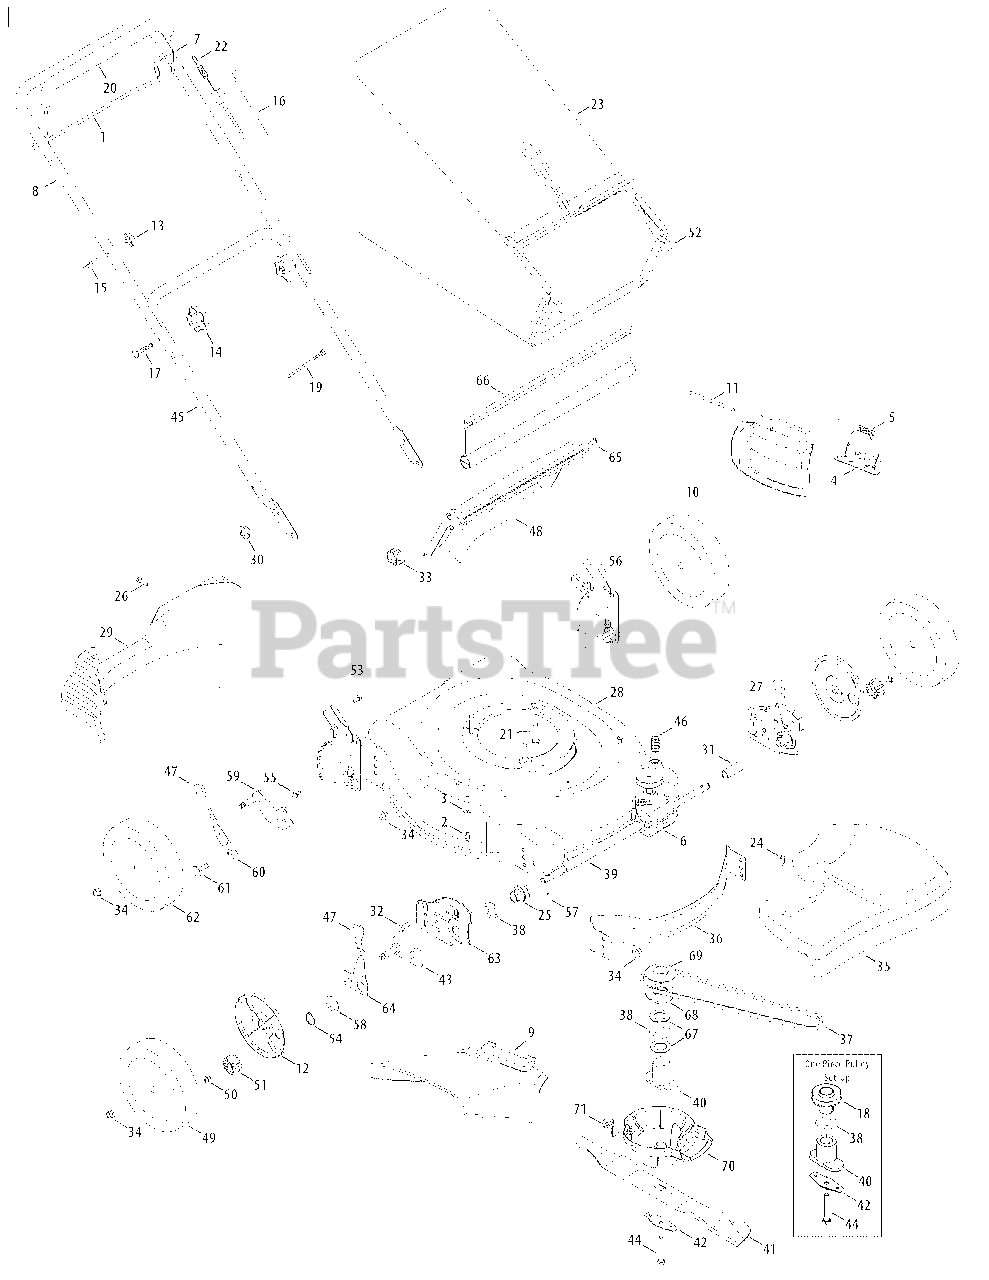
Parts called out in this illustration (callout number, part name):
1	Drive Control
2	TT Screw 1/4-20 x 0.5
3	Bell Washer.265 x 0.75
4	Deflector Chute Adapter
5	Torsion Spring
6	Transmission Assembly
7	Blade Control
9	Chute Deflector
10	Mulch Plug Complete
11	Hinge Pin
12	Wheel Dust Cap
13	Handle Knob
14	Star Knob
16	Control Cable - 40.75"
17	Carriage Bolt 5/16-18 x 2.0
18	Pulley Assembly, Drive
19	Cable Tie
20	Bail Cover
21	Self-Tapping Sems Screw
22	Drive Cable - 51"
23	Grassbag
24	Shoulder Screw # 12 -24
25	Front Bearing Assembly
26	Screw, 1/4-15 x 1.000
27	Height Adjustment Ass’y - RH
27	Height Adjustment Ass’y - LH
29	Rear Baffle
30	Wing Nut
31	Slev. Spacer 1.4" Lg.
32	Hex Screw, 3/8-16 x.75
33	Torsion Spring - RH
34	Flange Lock Nut, 3/8-16
35	Transmission Cover
36	Front Baffle
38	Wave Washer
39	Sleeve Spacer 8.985" Lg.
40	Blade Adapter, 25mm
41	21" Mulching Blade
42	Blade Bell Support
43	Pivot Plate Assembly
44	Hex Screw 3/8-24 x 2.50
46	Belt Tension Spring
47	Adjustment Knob
48	Rear Discharge Door
49	Front Wheel
50	Screw, 1/4-20 x .390
51	Gear 14T RH FWD
51	Gear 14T LH FWD
53	Carriage Bolt 1/4-20
54	Snap Ring
55	TT Scr. w/Washer 1/4-20 x.625
56	Handle Bracket Assembly - RH
56	Handle Bracket Assembly - LH
57	Dowel Pin
59	Pivot Arm Assembly - RH
59	Pivot Arm Assembly - LH
60	Rear Spring Lever
61	Shoulder Scr.500 Dia. x.434
62	Rear Wheel
63	Height Adjuster Plate - RH
63	Height Adjuster Plate - LH
64	Front Lever - RH
64	Front Lever - LH
66	Rear Trailing Shield
67	Washer, Flat, 1.031 x 1.620 x .095
68	Pulley, Half
69	Pulley, Half
70	Engine Baffle
71	Engine Baffle Bracket
